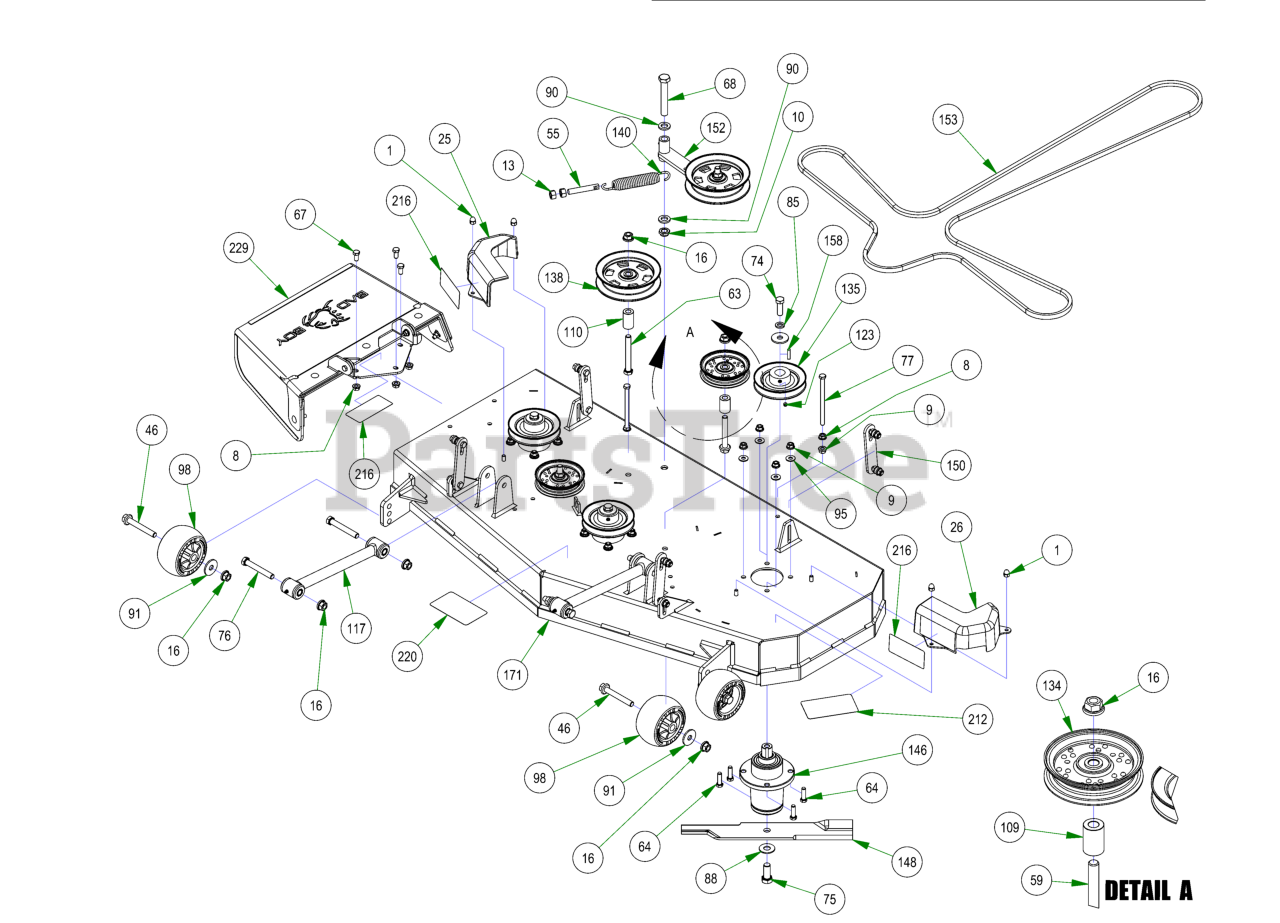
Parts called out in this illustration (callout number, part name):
1	5/16-18 ACORN NUT HIGH-CROWN ZC
8	3/8-16 HEX SERRATED FLANGE NUT HARD/ZINC
9	3/8-16 NYLON INSERT FLANGE LOCKNUT (GR.F) ZINC
10	5/8-11 NYLON INSERT JAM LOCKNUT ZINC
13	1/2-13 HEX NUT ZINC
16	1/2-13 NYLON INSERT FLANGE LOCKNUT ZINC
25	pulley cover chute side
26	pulley cover non-chute side
46	1/2-13 X 90MM HEX FLANGE BOLT W/SHOULDER (GR.8) ZINC
55	All Thread
59	1/2-13 X 3-1/2 HEX FLANGE BOLT (GR.8) ZINC
63	1/2-13 X 4 HEX CAP SCREW (GR.8) ZINC YELLOW
64	3/8-16 X 1-1/4 HEX CAP SCREW (GR.5) ZINC
67	3/8-16 X 3/4 HEX CAP SCREW (GR.5) ZINC
68	5/8-11 X 4 HEX CAP SCREW (GR.8) ZINC YELLOW
74	1/2-20 X 1-1/2 HEX CAP SCREW (GR.5) ZINC
75	5/8-18 X 1-1/2 HEX CAP SCREW (GR.8) ZINC YELLOW
76	1/2-13 X 3-1/2 HEX CAP SCREW (GR.5) ZINC
77	3/8-16 X 5-1/2 HEX CAP SCREW (GR.5) ZINC
85	1/2 SPLIT LOCKWASHER (GR.8) ZINC/YELLOW
88	5/8 USS FLAT WASHER (1-3/4" OD) GR.8 ZINC YELLOW
90	.635 ID X 1.120 OD X .140 THICK FLAT WASHER NYLON
91	1/2 BELLEVILLE WASHER (1-5/8 OD X .140 THK) ZINC
95	5/16 USS FLAT WASHER (7/8 OD) ZINC
98	Deck Wheel
109	.502 ID X .750 OD X 1.500 Long Spacer
110	1 3/4" Pulley Spacer
117	Hybrid Turnbuckle/Deck Locator
123	5/16-24 X 1/4 SOCKET SET SCREW (CUP PT) PLAIN
134	4 3/4 Idler Pulley - ABFI-76
135	5" Spindle Deck Pulley
138	5-3/4 Idler Pulley
140	Deck Idler Spring
146	Spindle Assembly
148	48" ZT/Mav/Compact Outlaw Blade with Fusion
150	Deck Hanger Assembly
152	2017 MZ/ZT Deck Idler Assembly
153	B147 Deck Belt
158	1/4 X 1 SQ MACHINERY KEY 1018 STL PLN
171	2023 48" x 5" Deck
212	2018 48" Deck Decal
216	Danger Decal-Spindle/Discharge
220	Deck Belt Route Decal
229	ZT Chute Assembly
